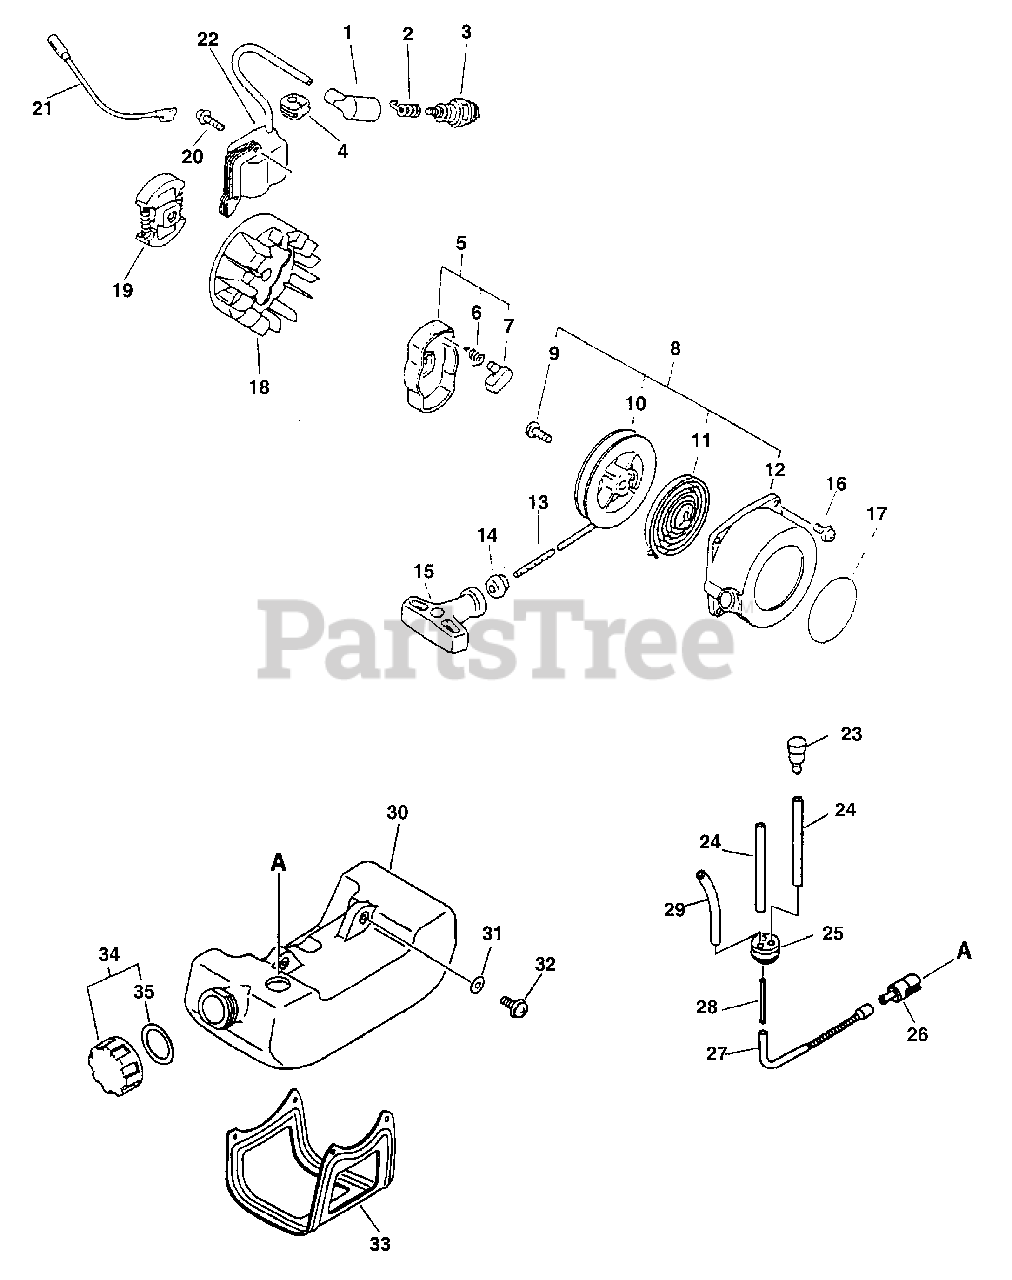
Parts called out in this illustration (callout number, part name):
1	CAP, SPARK PLUG
2	TERMINAL, SPARK PLUG
3	SPARK PLUG - BPM-7Y
3	SPARK PLUG - RCJ7Y
5	PAWL ASSY, STARTER
6	SPRING, RETURN
7	PAWL, STARTER - BLACK
8	STARTER ASSY, RECOIL
9	SCREW
10	REEL, ROPE
11	SPRING, RECOIL
12	CASE, RECOIL STARTER
14	GUIDE, ROPE
15	GRIP, STARTER
16	BOLT 4×16
17	LABEL, ECHO
19	CLUTCH ASSY
20	SCREW 4×22
21	LEAD
22	COIL, IGNITION
23	VENT ASSY
24	PIPE, FUEL 3x-5x-70 BLACK
25	GROMMET, FUEL
26	FILTER, FUEL
27	PIPE, FUEL 3×7×100 FLEXIBLE
28	CONNECTOR, PIPE
29	PIPE, FUEL RETURN 3×6×90 MM CLEAR
30	TANK, FUEL
31	WASHER 5.5×12×0.8
32	SCREW 5×16
33	GUARD, FUEL TANK
34	CAP ASSY, FUEL
35	GASKET, FUEL CAP
